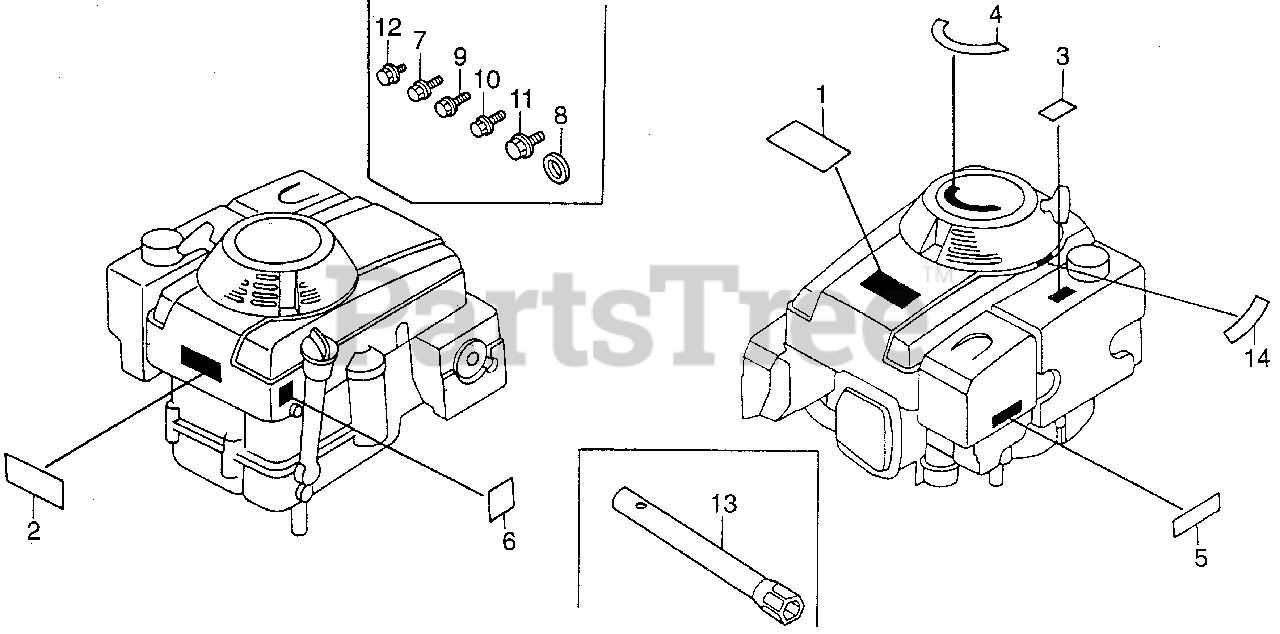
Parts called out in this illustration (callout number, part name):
1	EMBLEM, TOP COVER (E)
2	LABEL, EMBLEM (H)
3	LABEL, FUEL CAUTION (ENGLISH)
4	MARK, EASY START (ENGLISH)
5	MARK, AIR CLEANER CAUTION
6	MARK, OIL CAUTION
13	WRENCH, BOX (P21)
